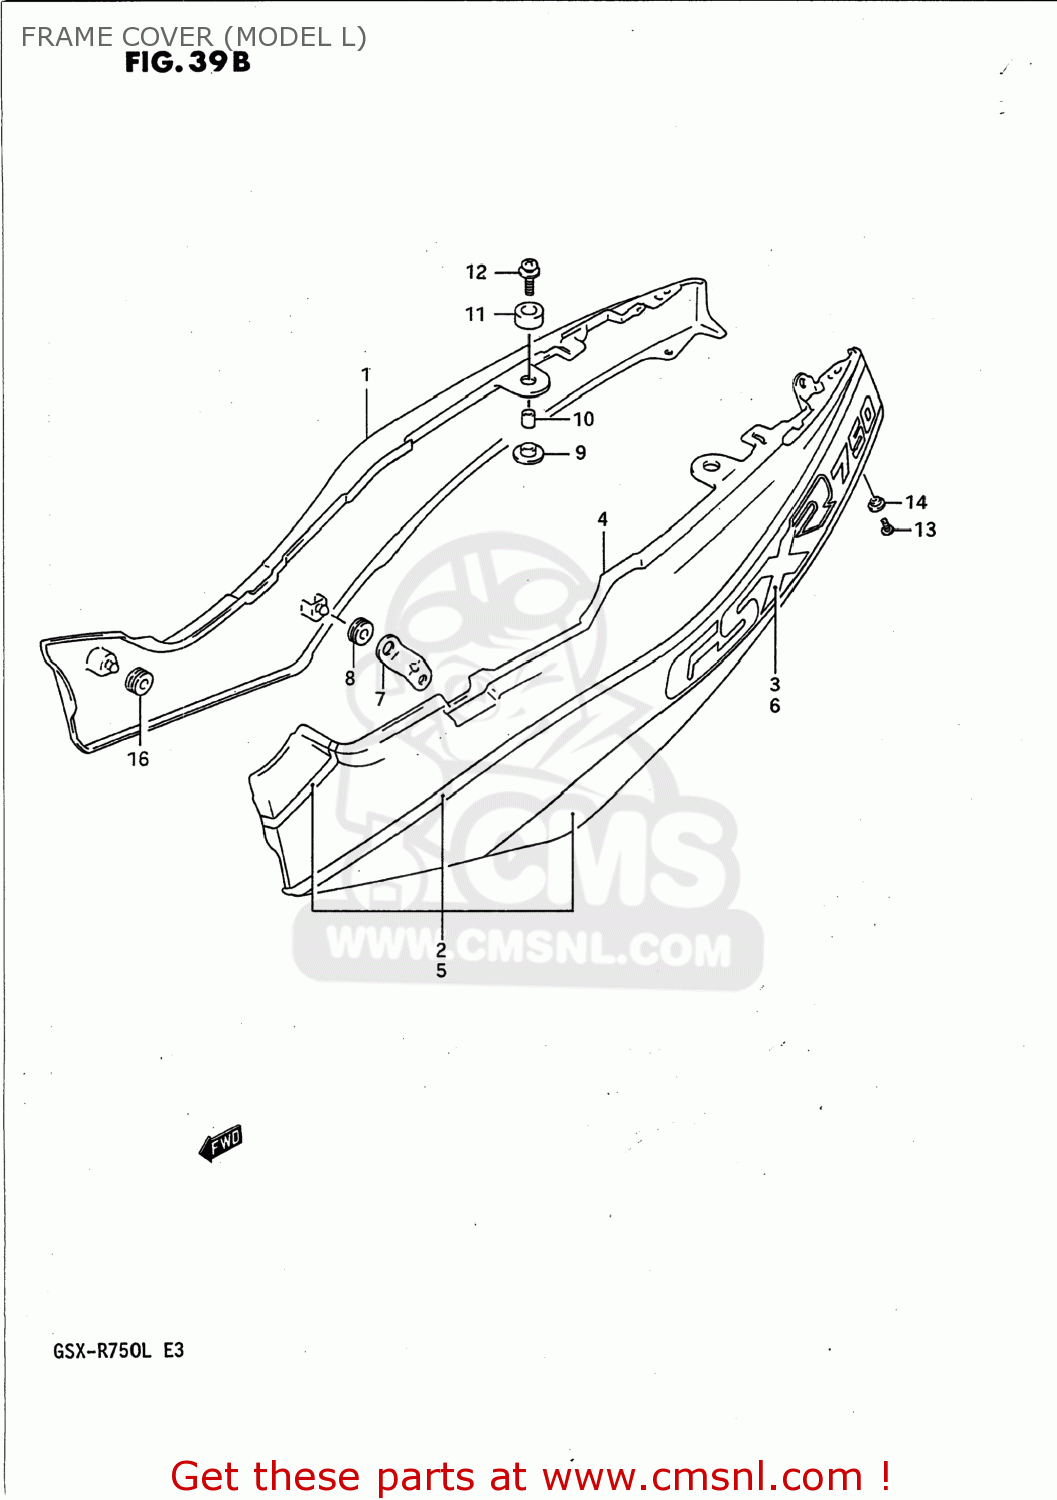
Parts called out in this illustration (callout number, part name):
1	COVER,FRAME,R
2	TAPE SET,FRAME COVER STRIPE
3	EMBLEM,FRAME COVER
4	COVER COMP,FRAME,LEFT
5	TAPE SET,FRAME COVER STRIPE
6	EMBLEM,FRAME COVER
7	BRACKET,FRAME COVER
8	CUSHION
9	CUSHION,FRAME COVER LWR
10	SPACER
11	CUSHION,TAIL COVER UPR
12	SCREW(6X30)
13	SCREW, FRONT & REAR
14	WASHER(5.2X14X1.5)
